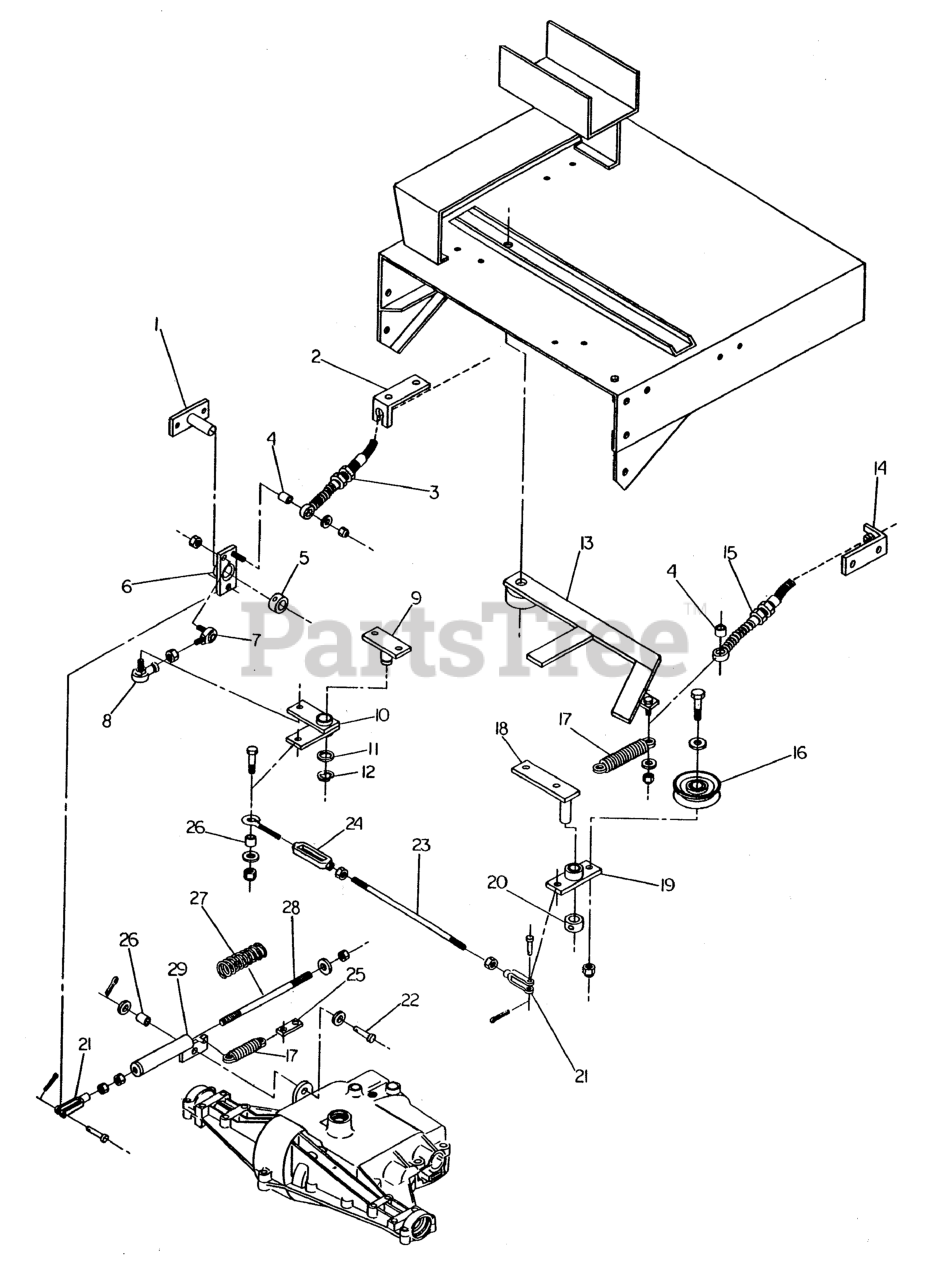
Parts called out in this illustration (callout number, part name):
1	Brake Pivot Bracket
2	Brake Cable Weld.
3	Clutch Cable
4	SPACER, .26 X .38 X .50
5	COLLAR, 3/4" Set
6	Brake Pivot
7	Male Ball Joint
8	BALL JOINT 5/16-24 LH FEMALE W/STUD, BR
9	Pivot Bracket
10	Brake - Clutch Pivot
11	SHIM
12	C-CLIP
13	Clutch Arm
14	Clutch Cable Bracket
15	Clutch Cable
16	Idler Pulley
17	SPRING, Extension
18	Pivot Bracket
19	Idler Pivot Weldment
20	COLLAR, 3/4" Set
21	CLEVIS, 5/16-24, Plastic
22	CLEVIS PIN, 3/8 x 3/4
23	Brake Linkage Rod
24	TURNBUCKLE ASSY
25	Brake Return Bracket
27	SPRING, Compression
28	Brake Overload Rod
29	Brake Overload Tube
